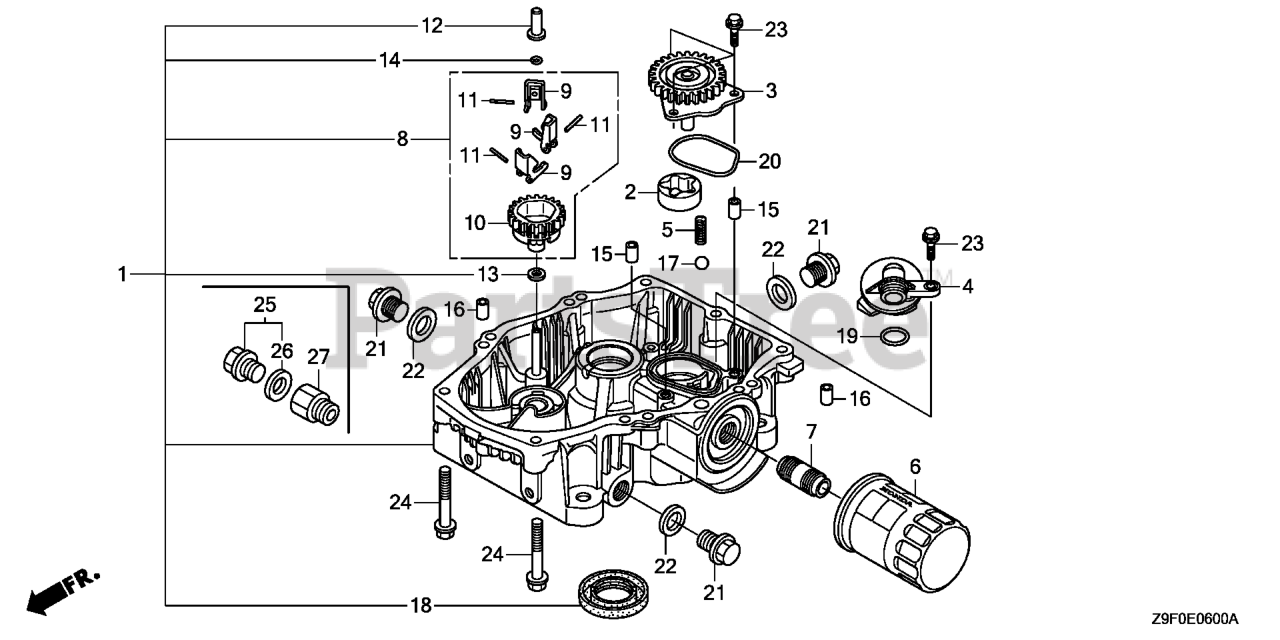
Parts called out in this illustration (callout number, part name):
1	PAN ASSY., OIL
2	ROTOR, OIL PUMP (OUTER)
3	GEAR, OIL PUMP
4	STRAINER, OIL
5	SPRING, RELIEF VALVE
6	FILTER, OIL (FILTECH TOYO ROKI) (SOLD INDIVIDUALLY)
6	FILTER, OIL (HONEYWELL) (SOLD IN MULTIPLES OF 30)
6	FILTER, OIL
7	HOLDER, OIL FILTER
8	GOVERNOR ASSY.
9	WEIGHT, GOVERNOR
10	HOLDER, GOVERNOR WEIGHT
11	PIN, GOVERNOR WEIGHT
12	SLIDER, GOVERNOR
13	WASHER (6X16)
14	CLIP, GOVERNOR HOLDER
15	PIN, DOWEL (8X10)
16	PIN, DOWEL (8X14)
17	BALL, STEEL (#15) (15/32)
18	OIL SEAL (38X58X9)
19	O-RING (14.8X2.4)
20	O-RING, OIL PUMP
21	BOLT, DRAIN PLUG (20MM)
22	WASHER, DRAIN PLUG (20MM)
23	BOLT, FLANGE (6X20)
24	BOLT, FLANGE (8X45)
